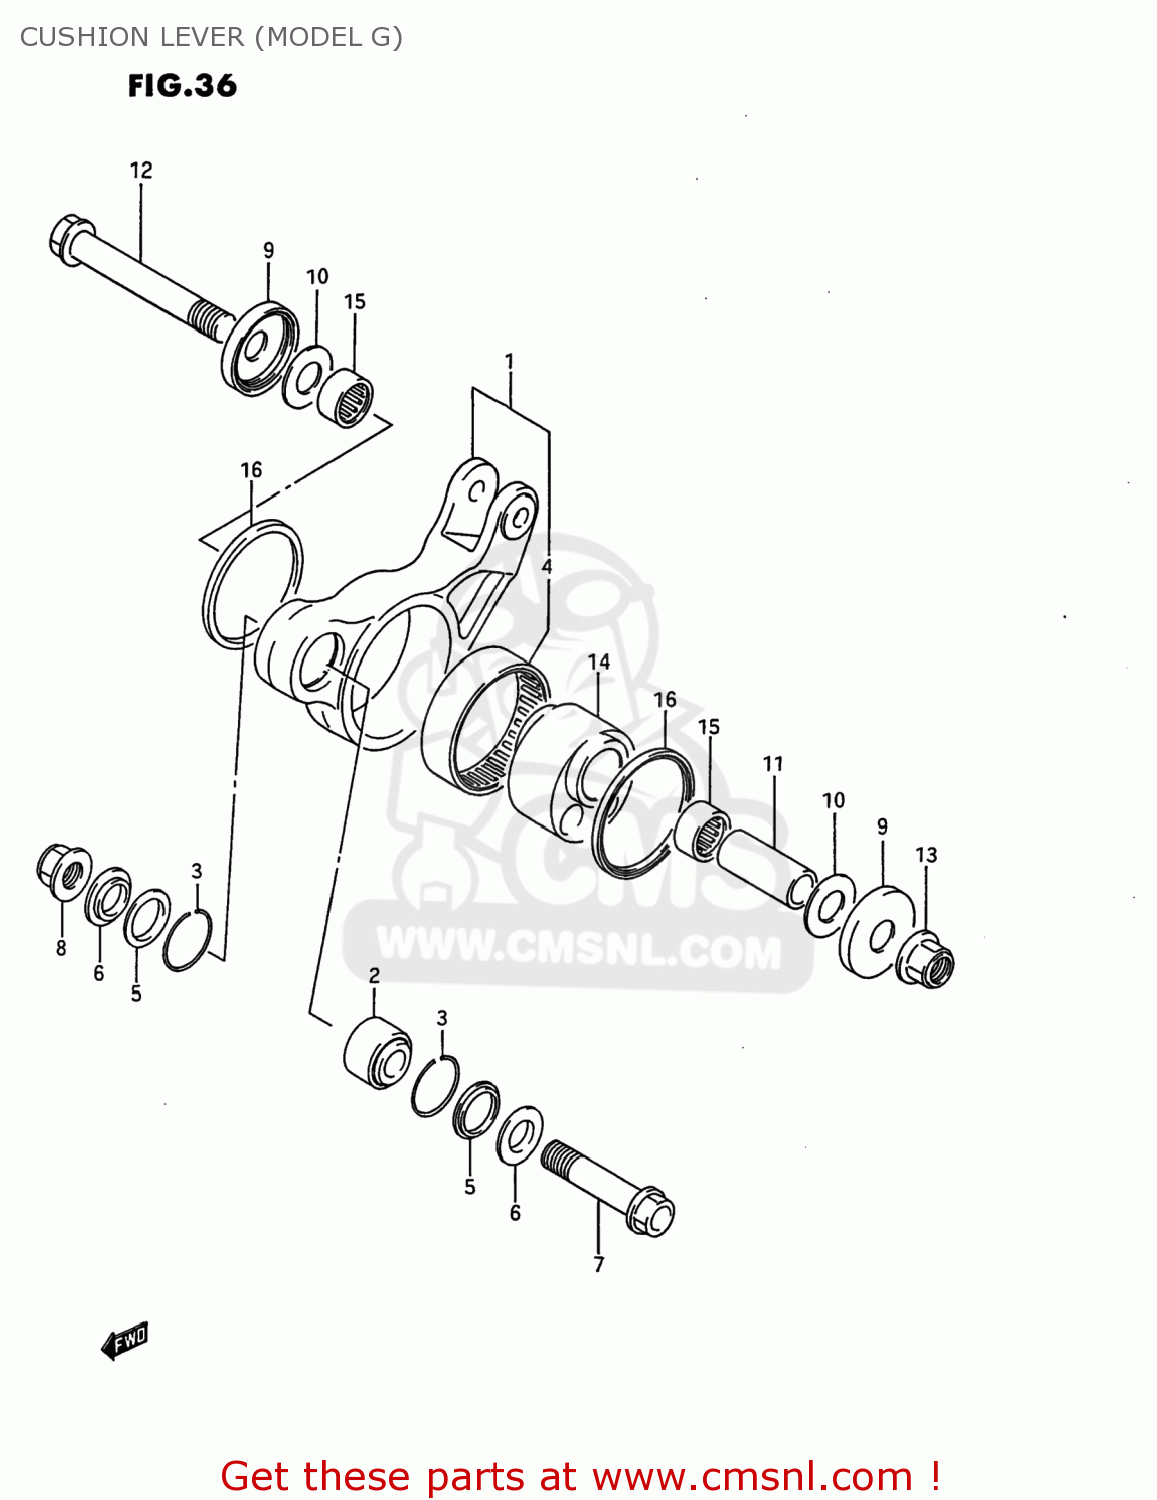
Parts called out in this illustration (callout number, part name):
1	LEVER SET,REAR CUSHION
2	SPHERICAL BEARING (14X2)
3	RING,BEARING STOPPER
4	BEARING(55X63X25)
5	SEAL,REAR CUSHION LEVER
6	SPACER,RR CUSHION LEVER FR
7	BOLT,RR CUSHION LEVER FR
8	NUT
9	DUST SEAL,RR C
10	WASHER
11	SPACER,REAR CUSHION LEVER
12	SHAFT,RR CUSHION LEVER
13	NUT
14	SPACER,REAR CUSHION ECCENTRIC
15	BEARING(20X27X20)
16	SEAL,RR CUSHION LEVER DUST
